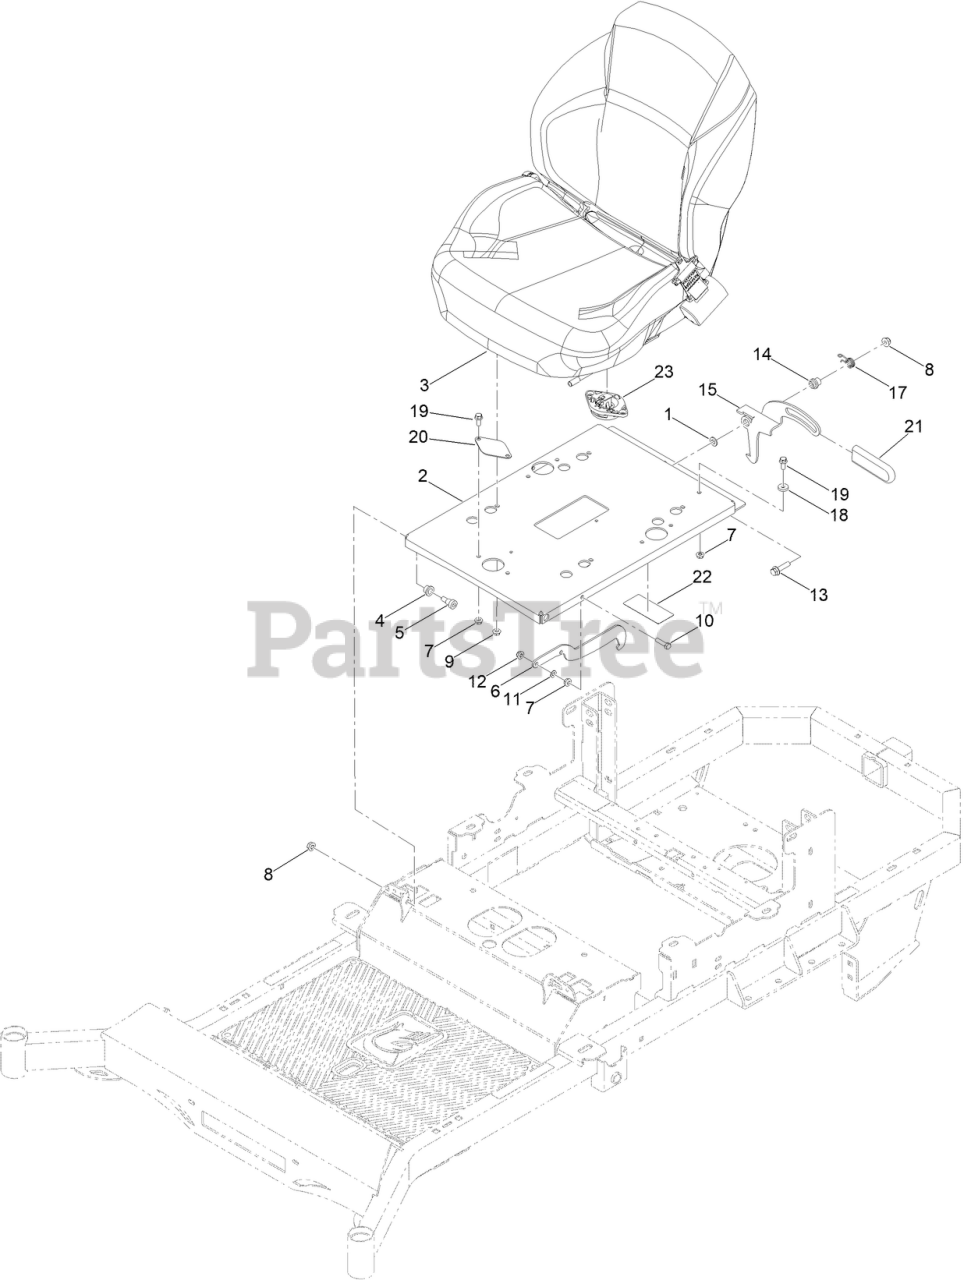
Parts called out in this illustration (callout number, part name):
1	WASHER-FLAT
2	NON 360 SEAT BASE PLATE SAFTY DECAL ASM-
3	RT PRO SEAT
4	1/2IN ID X 5/8IN OD X 1/2IN FLANGE BUSH
5	1/2 X 1/2 SOCKET SHOULDER BOLT ZC YELLOW
6	MWR SEAT LATCH HOOK PAINT
9	5/16-18 NYLON INSERT FLANGE L/NUT ZC
10	SCREW-HH
11	.312IDX.625ODX.062 THK THRUST BRG OI BRZ
12	NUT-HF, NI
13	SCREW-HHF
14	BUSHING-LATCH, SEAT
15	BRACKET-LATCH
17	SPRING-TORSION, LATCH
18	.312 ID X .875OD X .1875 THK F/W NYL
19	SCREW-HHF
20	2020 RT/SRT UNIV FLOAT SEAT CVR PLT
21	STAND UP MWR BRAKE ARM GRIP
22	DECAL-WARNING, BATTERY
23	MWR SEAT SWITCH
